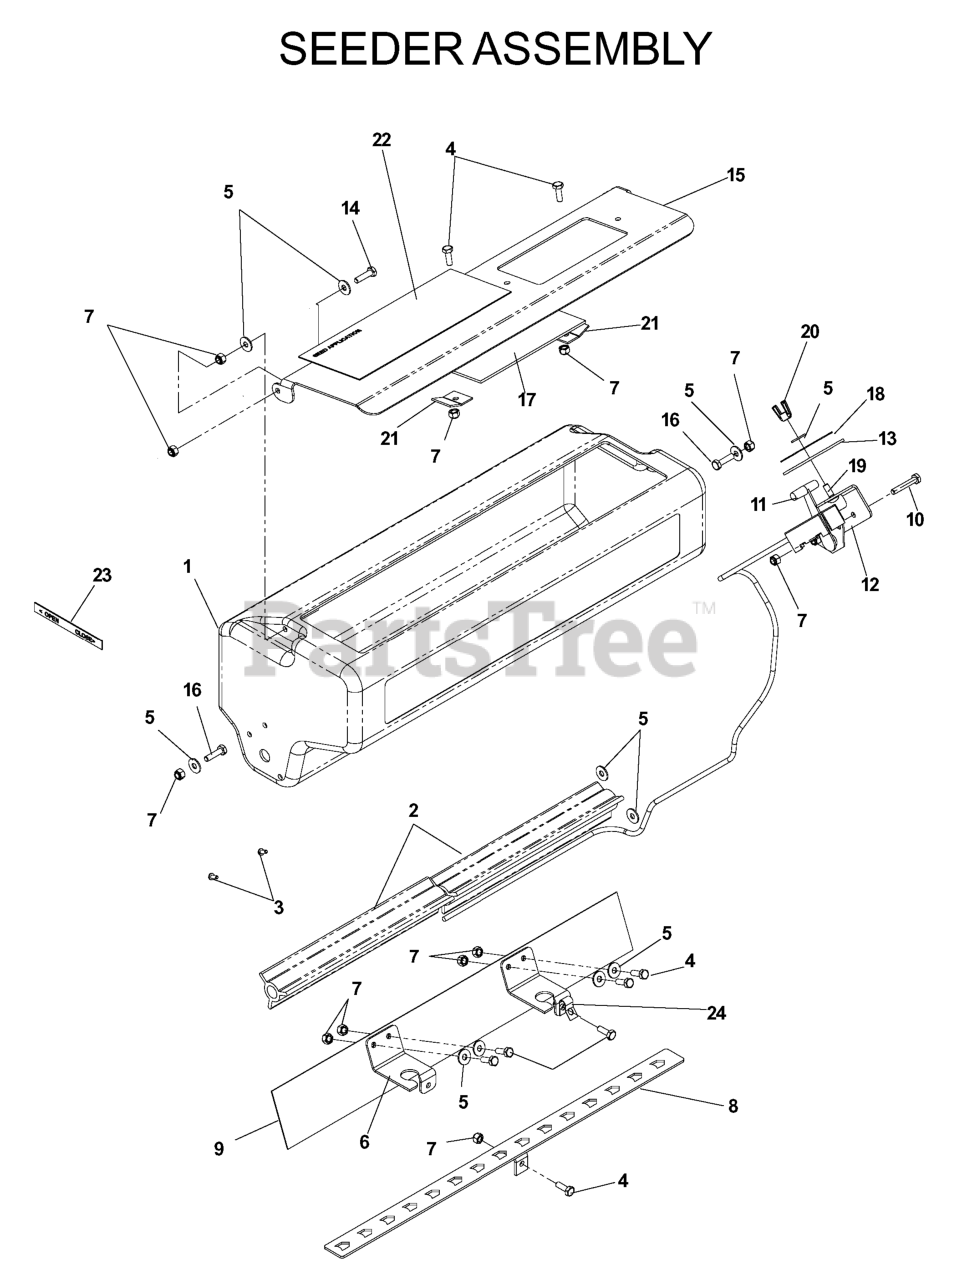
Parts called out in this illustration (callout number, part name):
1	SEEDBOX
3	R/B 108495 SCR SLF TP 8-32X3/8
4	HCS 1/4C X 3/4 HCS
5	WASHER 1/4 FLAT
7	NUT.1/4-20.HEX.NYLOC.ZD
9	R/B 109375 SHIELD
10	SCW 1/4-20 X 1-1/2 HEX
11	CONTROL, PUSH/PULL ASSEMBLY
14	HCS 1/4C X 1
15	SEED DOOR ORANGE
16	HCS 1/4 X 1
17	SEED WINDOW
18	DECAL, SEED DIAL
19	R/B 990316 BLT CRGE5/16-18X3/4
20	WING NUT 1/4
21	WINDOW CLIP
22	DECAL, SEED APPL
23	DECAL, OPEN/CLOSE
24	BRACKET, PUSH/PULL
